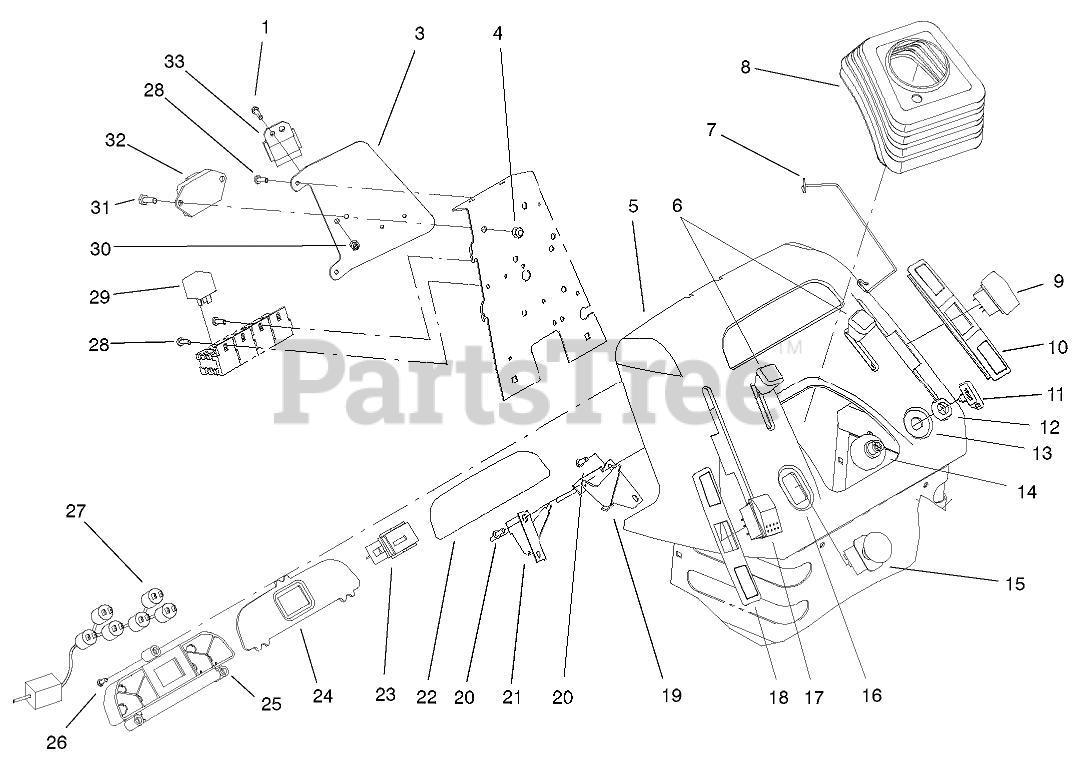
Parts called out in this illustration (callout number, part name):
3	PANEL-SUPPORT, AUX
4	NUT-LOCK, NI
7	CLIP-BOOT
8	BOOT-STEERING
9	SWITCH-CRUISE
10	Cover-RH Slot (onlyon: 72116)
10	Cover-RH Slot (onlyon: 72108)
11	KEY-IGNITION
13	Decal-Dash (onlyon: 72116)
13	Decal-Throttle,Ignition (only on:72108)
14	SWITCH-IGNITION
15	SWITCH-PTO
16	Decal-DashPTO/Choke (only on:72116)
16	Decal-PTO/Choke(only on: 72108)
17	SWITCH
18	Cover-Lift (only on:72116)
18	Cover-Lift (only on:72108)
19	CONTROL-THROTTLE (TWIN)
21	CONTROL-CHOKE (TWIN)
22	DECAL - DASH LENS
23	HOURMETER
24	LENS-DASH
25	HOUSING-LIGHT
26	SCREW
27	HARNESS-6 LAMP
28	SCREW-PPHTF
29	RELAY
30	NUT-LOCK, NI
31	SCREW-HH
32	MODULE-CLUTCH
33	MODULE-LOW VOLTAGE
